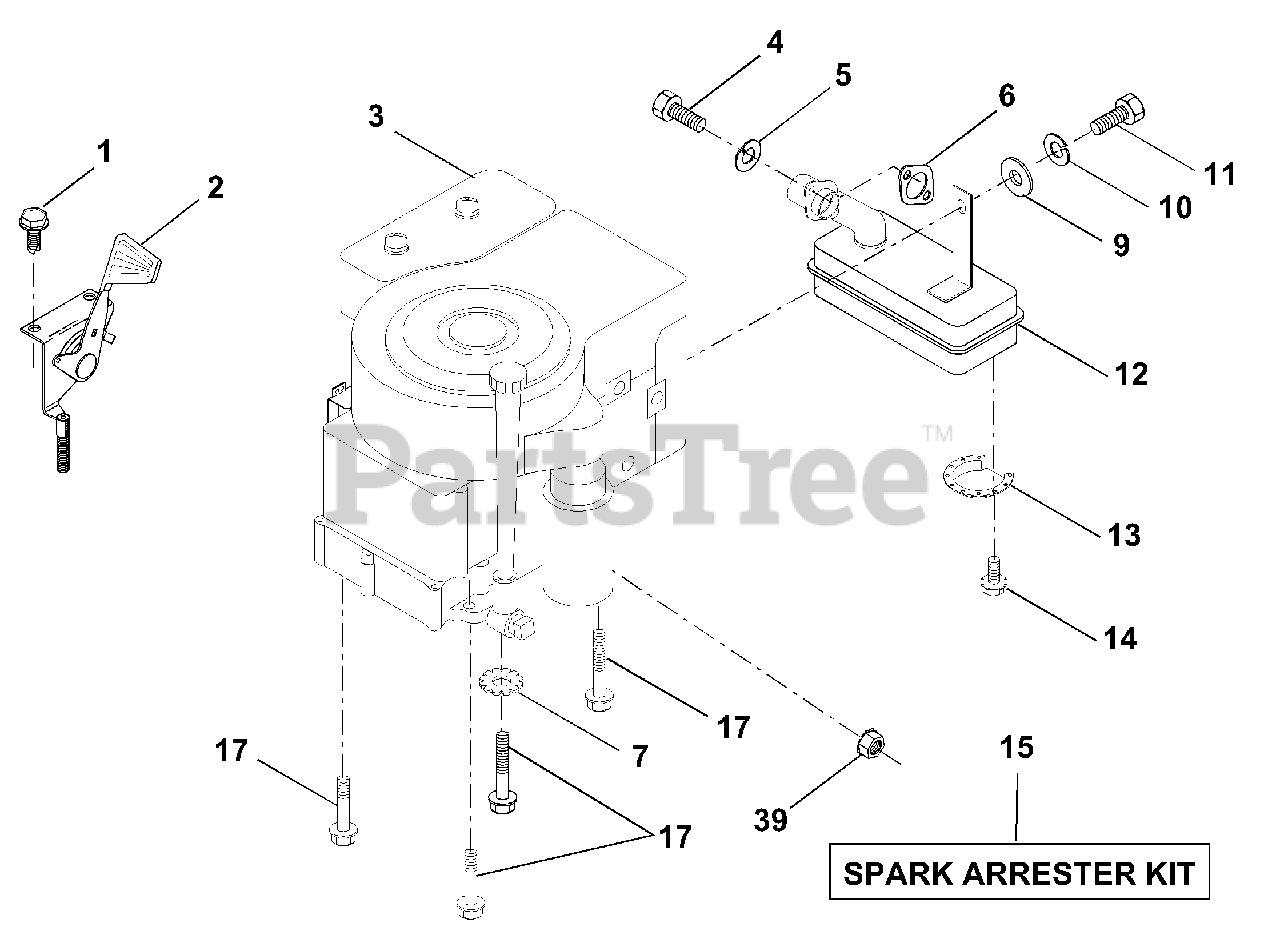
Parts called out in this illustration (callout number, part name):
1	Screw, Hex Thd. Cut 1/4-20 x 1/2
2	Control, Throttle
4	Screw, Hex, Cap 5/16-18 x 3/4
5	Washer, Lock Heavy Helical Spring 5/16
6	Gasket, Exhaust
7	Washer, Lock Ext. Tooth 3/8
9	Washer 5/16 x 3/4 x 16
10	Washer, Lock Hvy Hlcl Spring 1/4
11	Bolt, Hex Fin.
13	Deflector, Muffler
14	Screw, Spiderloc Hex Hd #8 x 1/2 AB
15	Arrester, Spark
17	Screw, Hex Washer Head, Thdrol. 3/8-16 x 1-1/2
39	Nut, Flange 1/4-20
